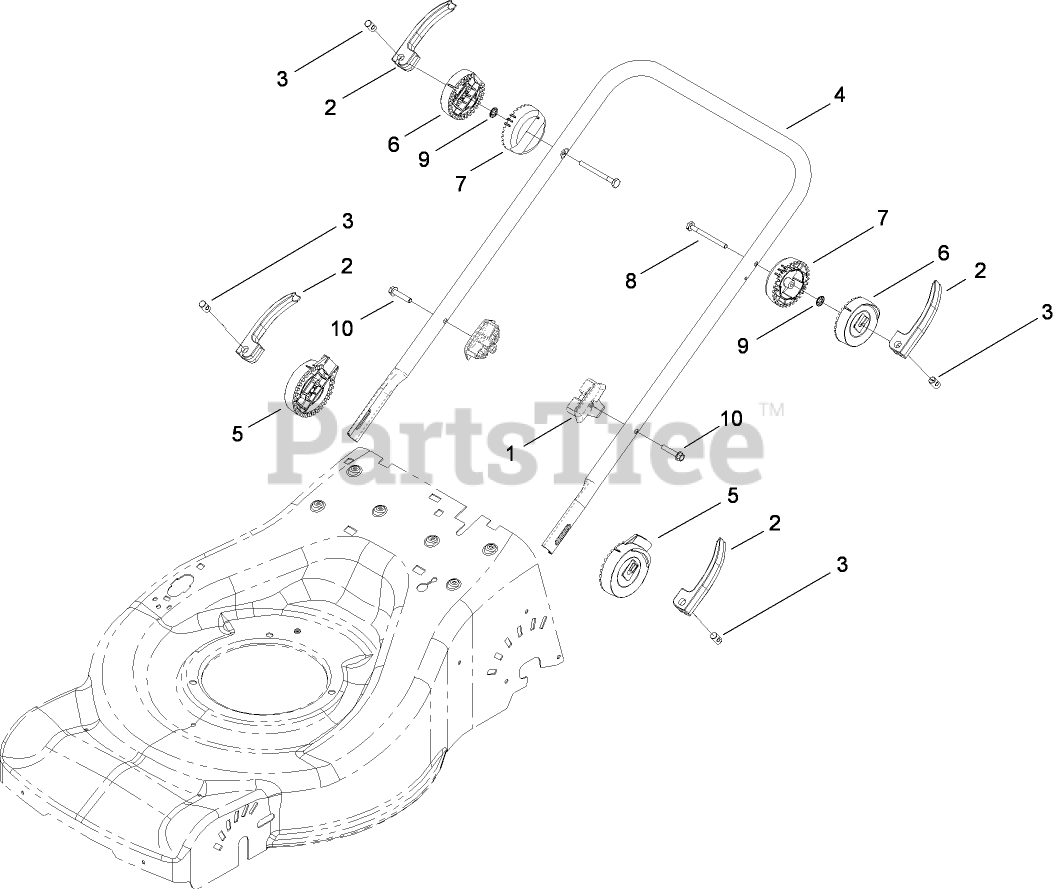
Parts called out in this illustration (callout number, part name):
1	ANCHOR-BAG
2	LEVER-LOCKING, HANDLE
3	PIVOT-PIN, THREADED
4	HANDLE-HOOP, LOWER
5	ADAPTER-RATCHET, LOWER
6	ADAPTER-RATCHET, MIDPOINT
7	ADAPTER-CLAMP, MIDPOINT
8	SCREW-HH
9	WASHER-STARLOCK, PUSH
10	SCREW-HWH
